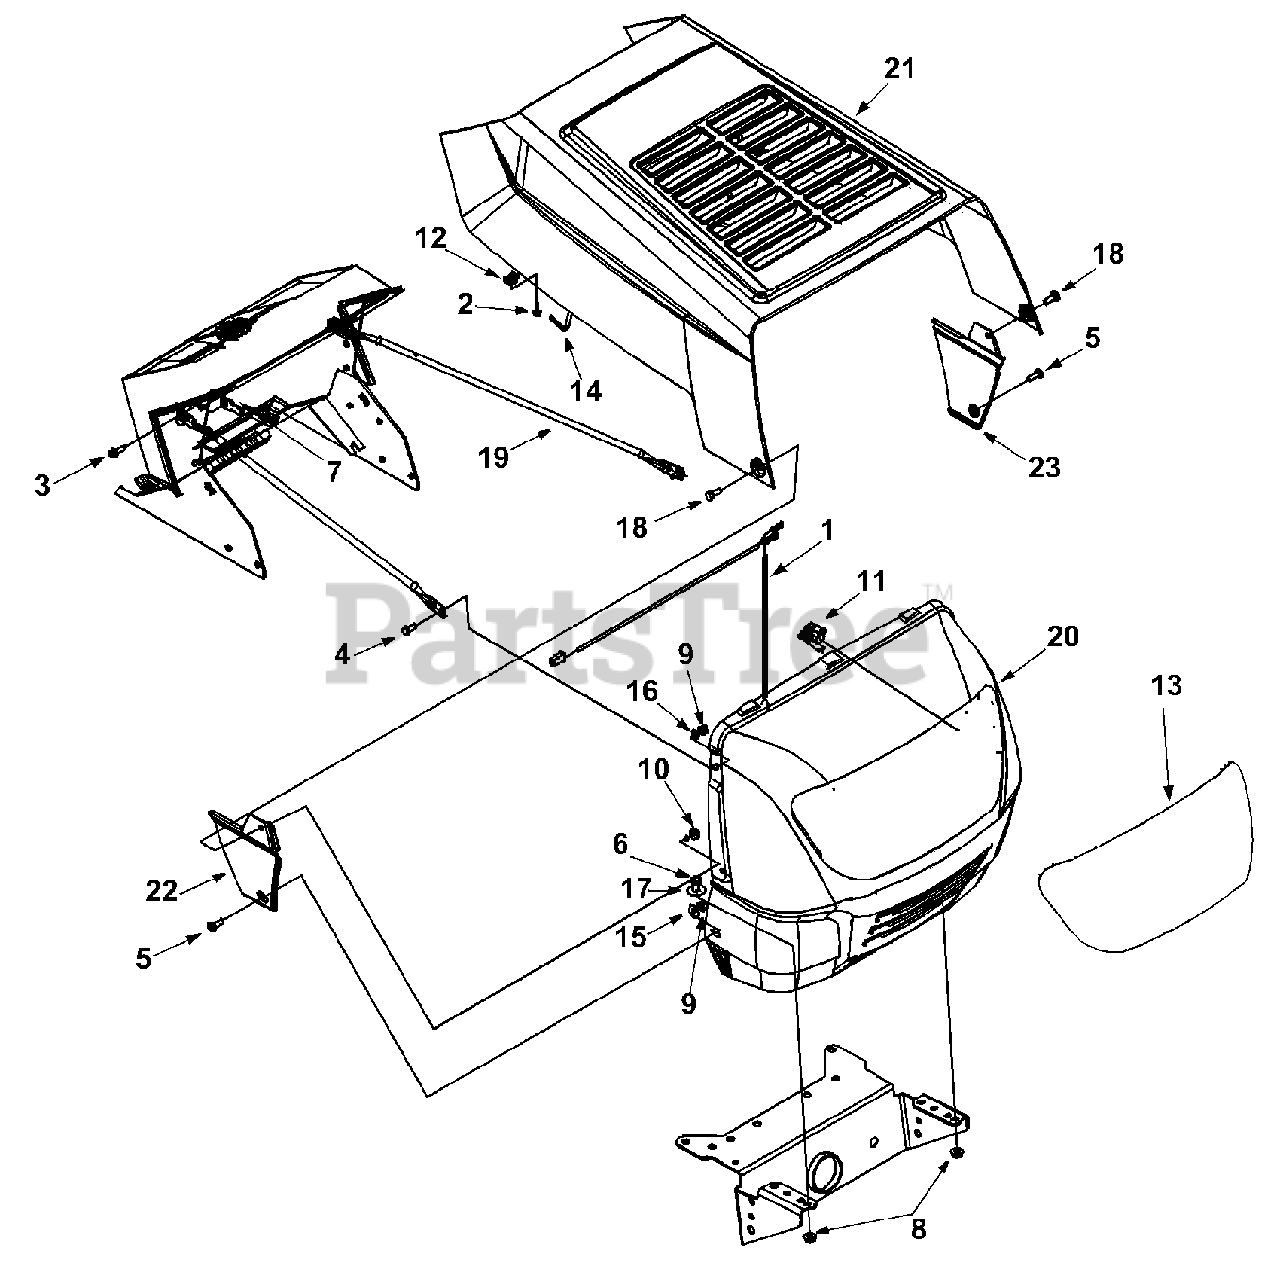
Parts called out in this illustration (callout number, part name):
1	Headlight Harness Assembly
2	Truss. Mach. Scr. #10-24 x .75"
3	Hex TT-Tap Scr. 1/4-20 x .75" Lg.
4	Hex Bolt 1/4-20 x .5/8" Lg.
5	Pan Hd. Mach. Scr. 1/4-20 x .75"
6	Hex Bolt 5/16-18 x .75" Lg.
7	Speed Nut 1/4-20 Thd.
8	Flange L-Nut 5/16-18 Thd.
9	Hex Sems Nut 1/4-20 Thd.
10	Hex Flange L-Nut 1/4-20 Thd.
11	Socket
12	Speed Nut
13	Lens
14	Hood Spring
15	Bell Wash. .265" I.D. x .75" O.D.
16	L-Wash. 1/4" I.D.
17	Fl-Wash. .349" I.D. x 1.0" O.D.
18	Shldr Bolt. .375" I.D. x 1.25" O.D.
